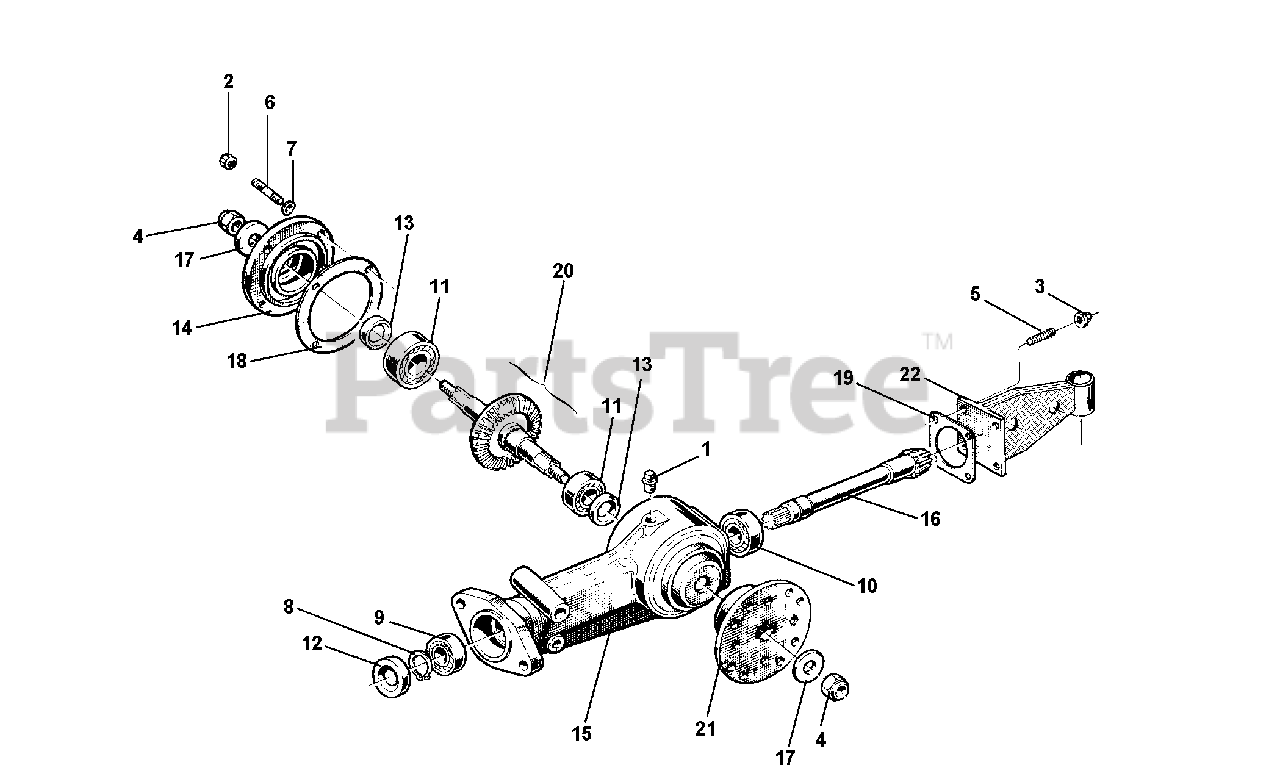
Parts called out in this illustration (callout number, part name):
1	PLUG 1/4 GAS
2	NUT, SELF LOCKING M8
4	NUT, SELF LOCKING M14 STANDARD
5	STUD M8 X 32 X 14 X 14
6	STUD M8 X 38 X 16 X 16
7	WASHER, LOCK 8.4
8	CIRCLIP EXTERN. D 20
9	BEARING 20 X 42 X 12 6004
10	BEARING 20 X 47 X 14 6204
11	BEARING 25 X 52 X 15 6205
12	SEAL, OIL 20 X 42 X 7 STANDARD
15	CASING OF ROTARY HOE 80 CM
16	PINION CONICAL
19	ROTARY HOE GASKET
20	SHAFT WITH GEAR
21	BLADE HOLDER FLANGE D 25
22	REAR COVER FOR ROTARY HOE
